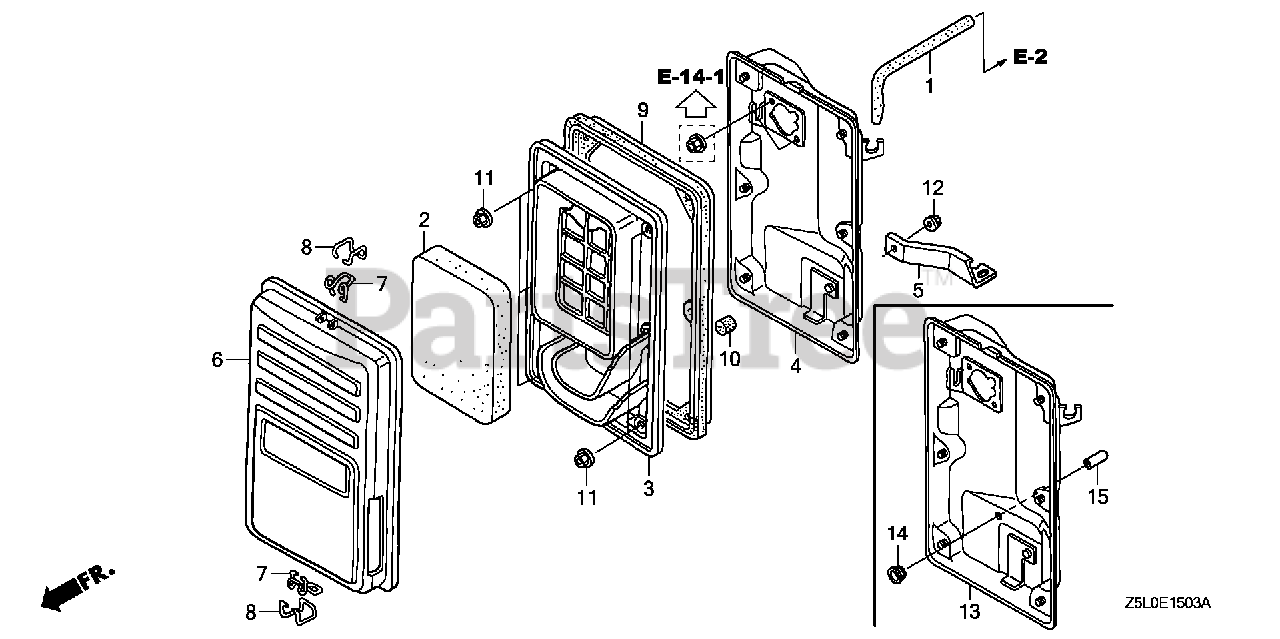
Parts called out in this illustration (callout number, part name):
1	TUBE, BREATHER
2	ELEMENT, AIR CLEANER
3	SEPARATOR, AIR CLEANER
4	HOUSING, AIR CLEANER
5	STAY, AIR CLEANER
6	COVER, AIR CLEANER
7	CLIP A, AIR CLEANER WIRE
8	CLIP B, AIR CLEANER WIRE
9	SEAL, AIR CLEANER
10	FILTER, DRAIN TUBE
11	NUT, FLANGE (5MM)
12	NUT, FLANGE (6MM)
13	HOUSING, AIR CLEANER
14	GROMMET, AIR CLEANER
15	CAP, SEALING
